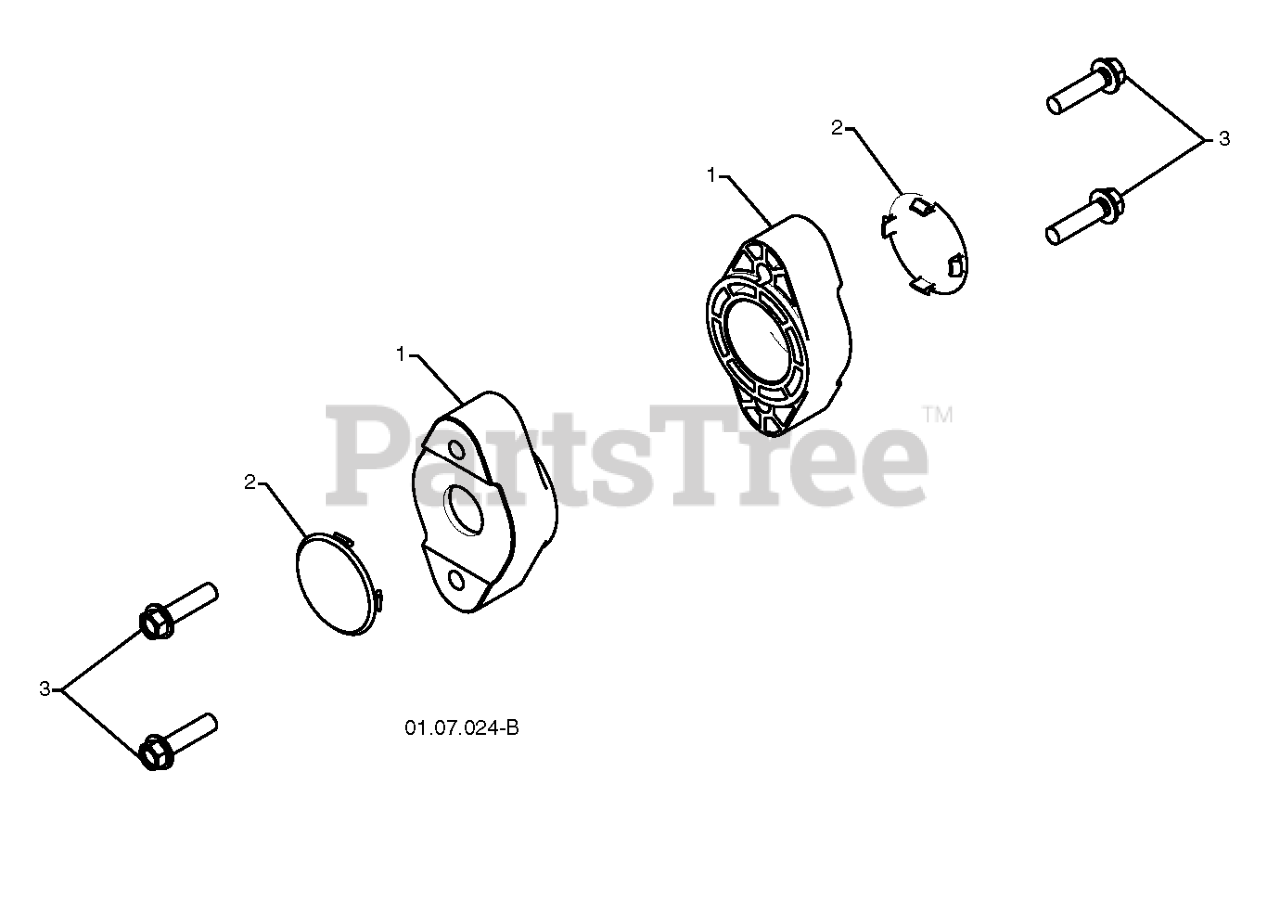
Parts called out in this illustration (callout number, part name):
1	BEARING.AUGER.SHAFT
2	PLUG.BEARING.HOLE.HSG
3	SCREW, HEX HD 5/16X1
